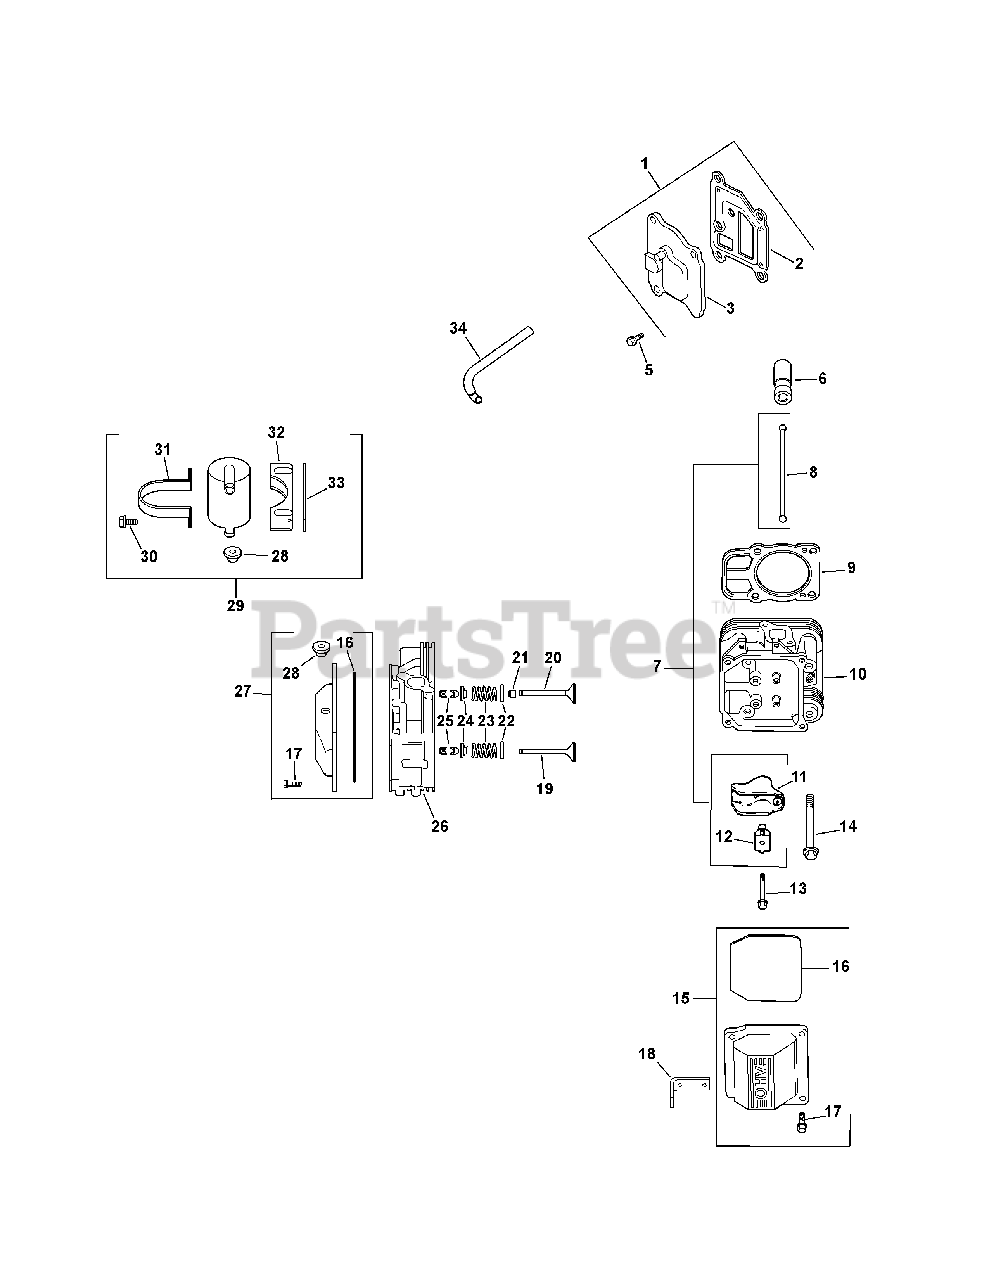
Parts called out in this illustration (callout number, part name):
1	KIT, BREATHER COVER W/GASKET
2	BREATHER GASKET
3	KIT, BREATHER COVER
4	PLUG, CTSK PIPE 1/8''
5	SCREW, FLG THD FRM M6X1.0X20
6	LIFTER, VALV! E HYDRAULIC
7	KIT, VALVE TRAIN
9	KIT, CYL HEAD GASKET(C730-745)
10	KIT, CYLINDER HEAD #2
12	PIVOT, ROCKER ARM
13	SCREW, FLG M6X1.0X34
14	SCREW,FLG M10X1.5X90
15	KIT, VALVE COVER-PLAIN
17	SCREW, SHOULDER
18	STRAP, LIFTING
19	VALVE, EXHAUST (STD)
19	VALVE, EXHAUST (.25)
20	VALVE, INTAKE (STD)
20	VALVE, INTAKE (.25)
21	SEAL, VALVE STEM
22	RETAINER, SPRING
23	SPRING, VALVE
24	CAP, VALVE SPRING
25	KIT, RETAINER
26	KIT, CYLINDER HEAD #1
27	KIT, BREATHER VALVE COVER
28	GROMMET, RUBBER
29	KIT, BREATHER SEPARATOR
30	SCREW, FLG THD FRM M5X0.8X16
31	STRAP, BREATHER
32	BRACKET, BREATHER SEPARATOR
34	BREATHER HOSE
